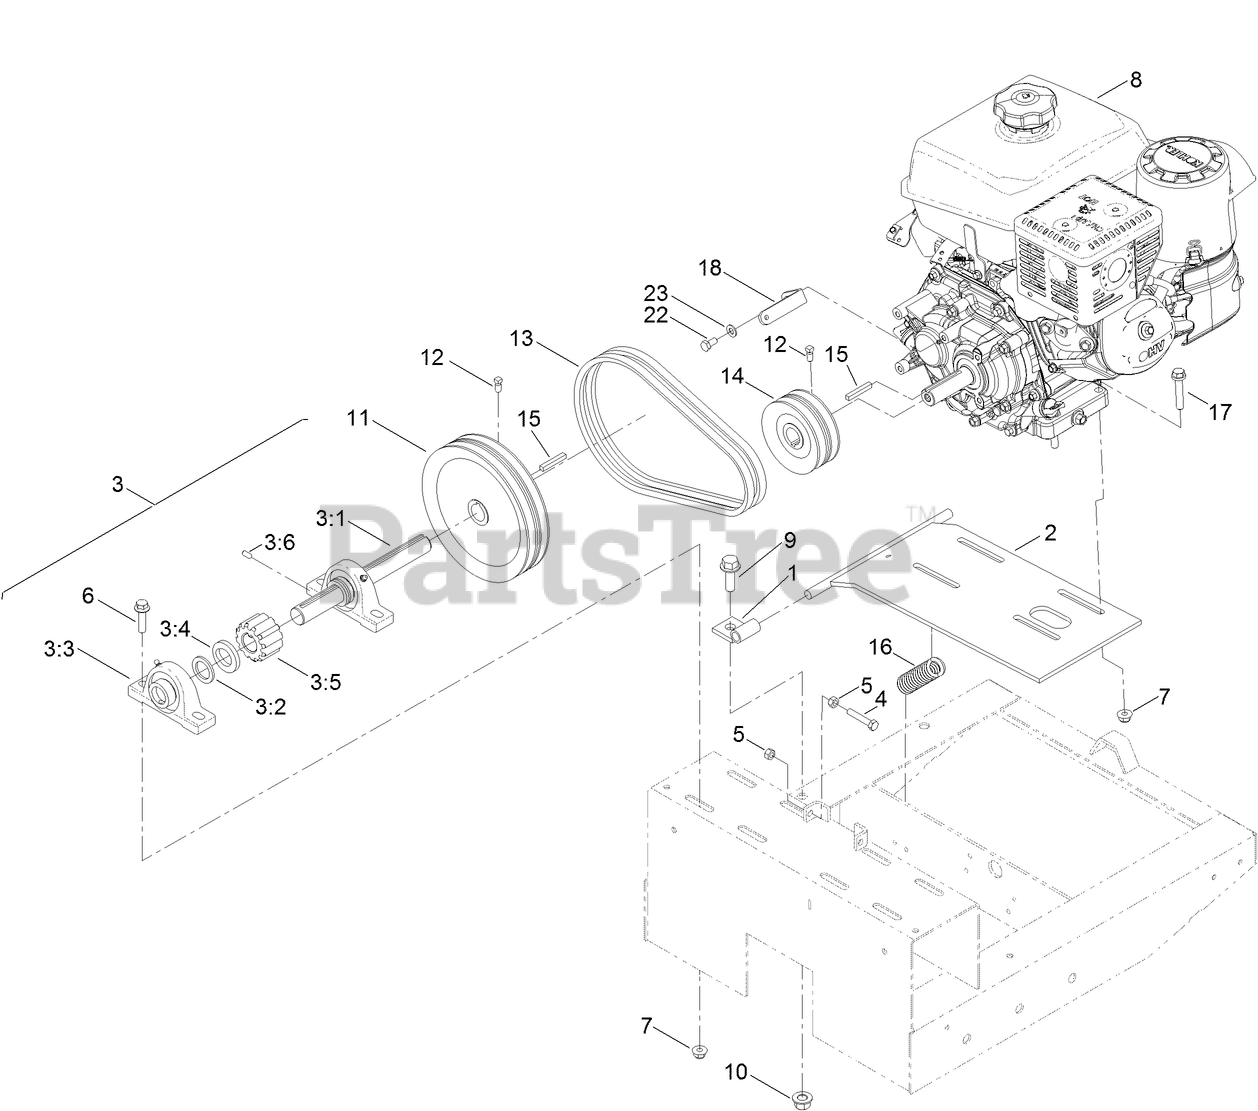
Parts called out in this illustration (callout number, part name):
1	MOUNT-MOTOR
2	BASE-MOTOR
3	PINION ASM
3:2	WASHER-THRUST
3:3	BEARING-BLOCK, PILLOW
3:4	WASHER
3:5	GEAR-SPUR
3:6	PIN-DOWEL
4	SCREW-HH
5	NUT-HEX
6	SCREW-HHF
7	NUT-HF, NI
8	ENGINE-KOHLER
9	SCREW-HHF
10	NUT-LOCK
11	SHEAVE
12	SCREW-SET
13	BELT-V (MATCHED PAIR)
14	SHEAVE
15	KEY-SQUARE
16	SPRING
17	SCREW-HHF
18	GUIDE-BELT
22	SCREW-HH
23	WASHER-PLAIN
